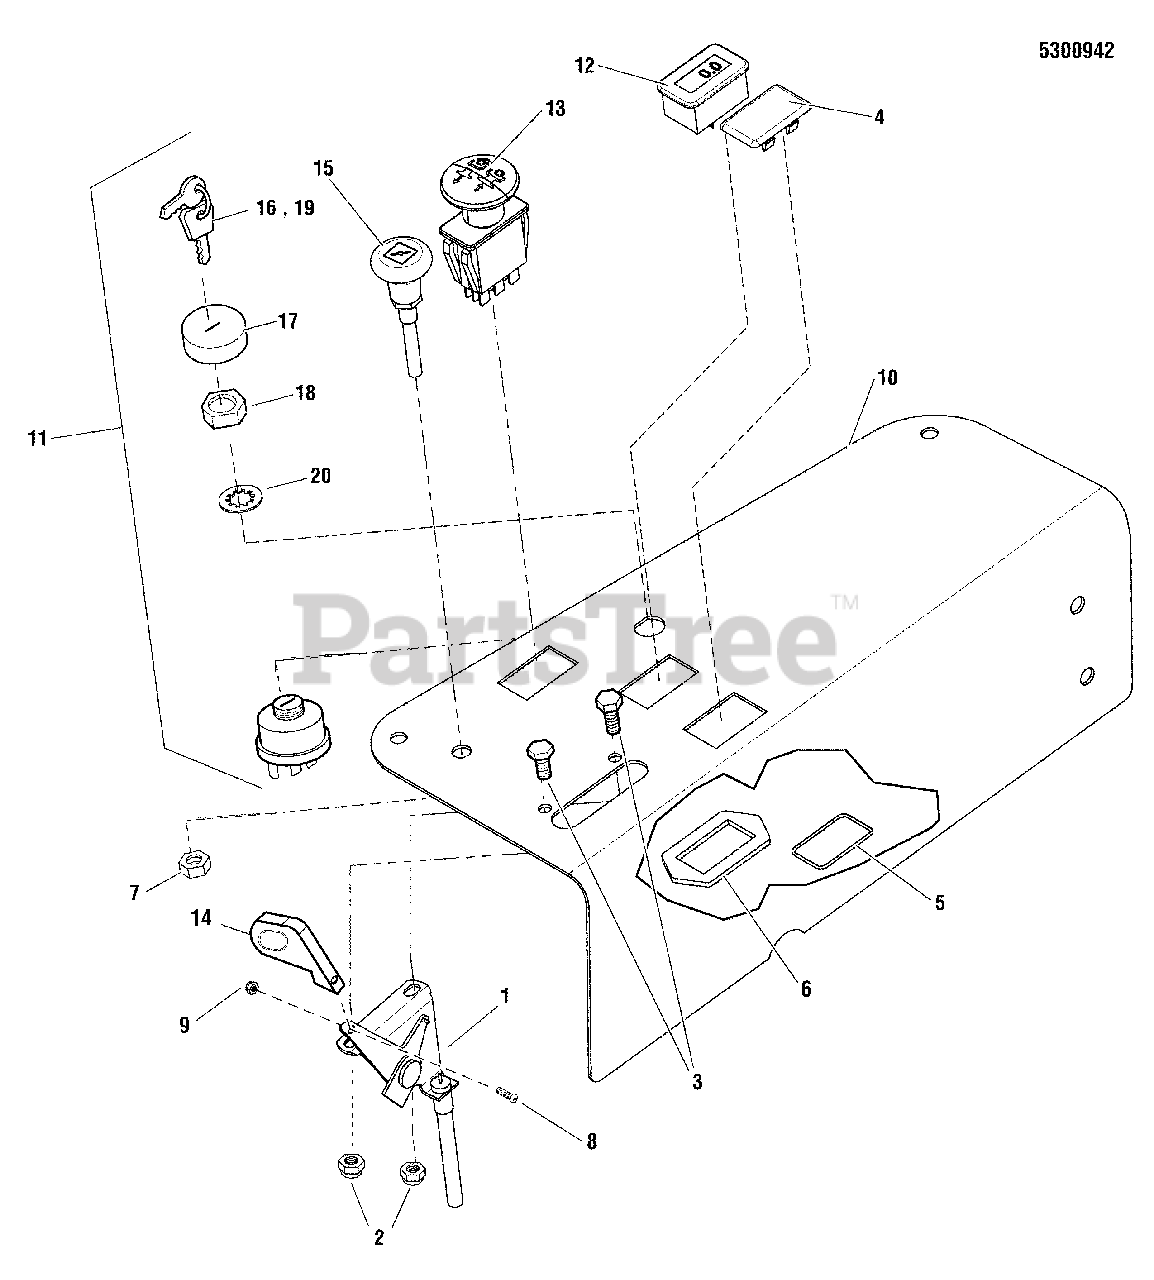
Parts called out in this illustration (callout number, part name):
1	CABLE, THROTTLE CONTROL, 36"
2	NUT, 1/4-20 HEX NYLON LOCK
3	BOLT, 1/4-20 X 3/4 GD5 YZ
4	PLUG, .820X1.44 HOLE, BLACK PLASTIC
5	O-RING, 7/8 ID X 1/16 W
6	RING, SWITCH RETAINER
7	NUT, 3/8-24 HEX
8	SCREW, #10-24 X 1" RS
9	NUT, #10-24 HEX NYLON LOCK
10	PLATE, CONTROL PANEL - BLACK
11	SWITCH ASMY-IGNITION INDAK NO KEYS
12	HOUR METER, W/ SUPRESSOR
13	SWITCH, BLADE ENGAGEMENT
14	KNOB-SLOTTED THROTTLE
15	CABLE, CHOKE CONTROL, 51"
16	KEYS. BLISTER PK KIDS+MWRS DON'T MIX, USA Models Only
17	COVER, SWITCH (SV)
18	NUT-HEX FLANGE 5/8-32 IGN SW DIE CAST (SV)
19	KEYS, BLISTER PK KIDS+MWRS DON'T MIX, EXP, CE MODELS ONLY
20	LOCKWASHER-INTERNAL TOOTH, .625 THIN BLK
